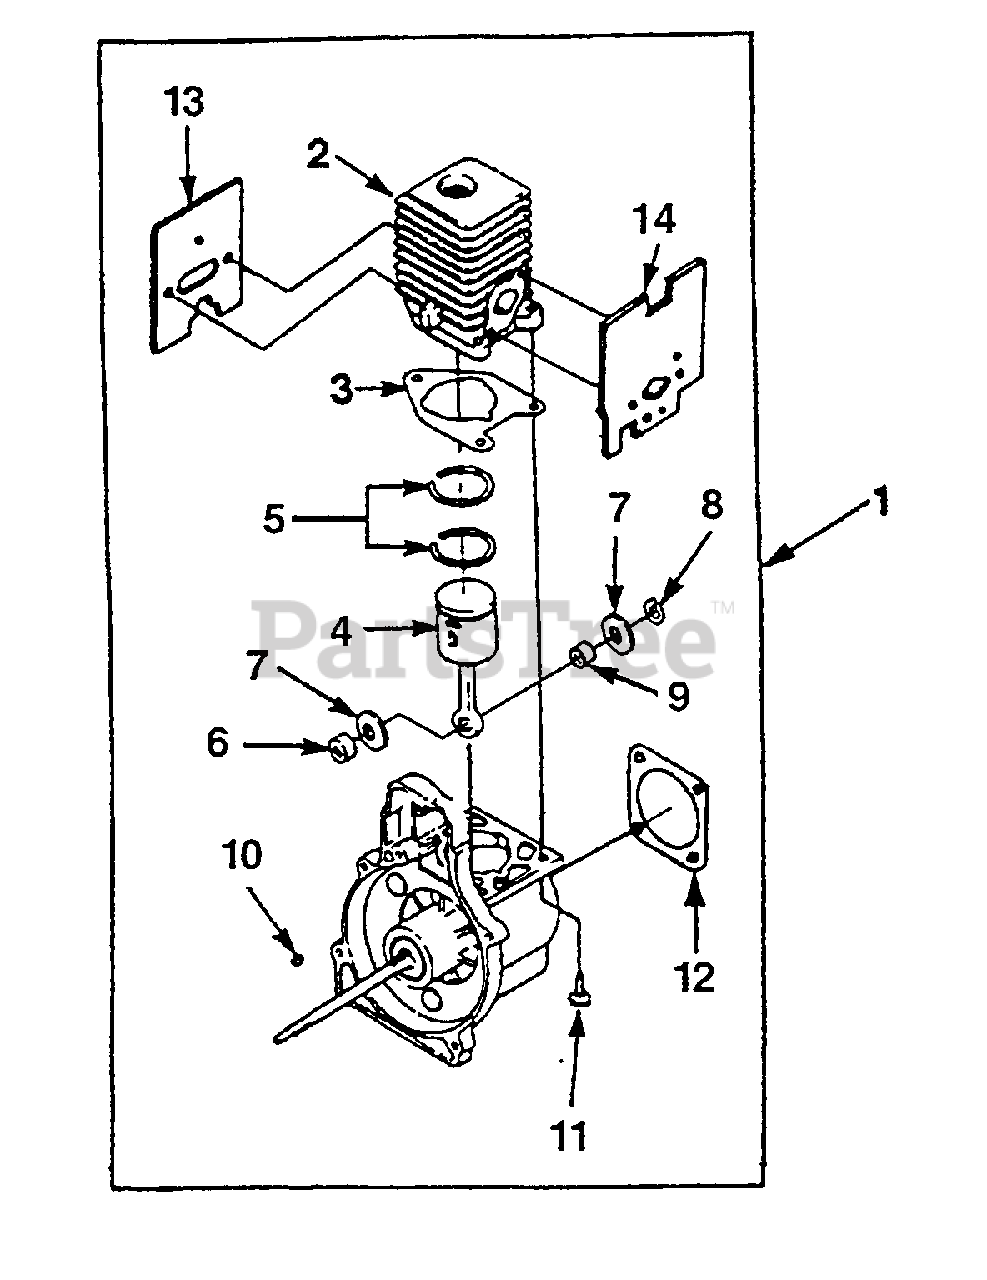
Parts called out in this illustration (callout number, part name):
1	SHORT BLOCK
2	CYLINDER & GASKET
3	GASKET-Cylinder
4	PISTON ROD
5	RING-Piston
6	SPACER-Bearing
7	WASHER-Thrust
8	RING-Retaining
9	BEARING-Needle
10	KEY-Woodruff
11	SCREW-Torx Pan Hd. (10-24 X 3/4")
12	GASKET-Crankcase
13	GASKET-Muffler
14	GASKET-Heat Dam
